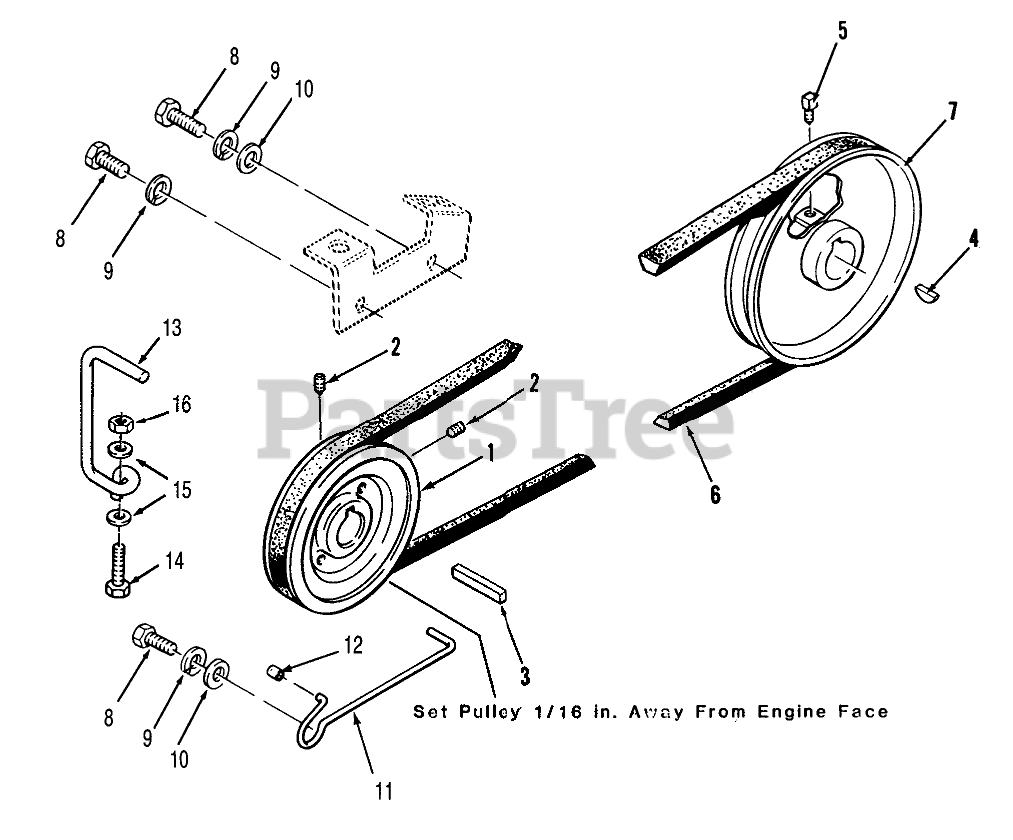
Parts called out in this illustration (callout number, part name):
1	PULLEY
2	Set Screw
4	KEY-HI PRO
5	Set Screw
6	V BELT
7	PULLEY-TRANSMISSION
8	7/16-14 x 1 1/4 Bolt
9	LOCKWASHER
10	WASHER
11	GUIDE BELT
13	GUIDE-BELT BOTTOM
14	Bolt
15	Collar
16	Nut
